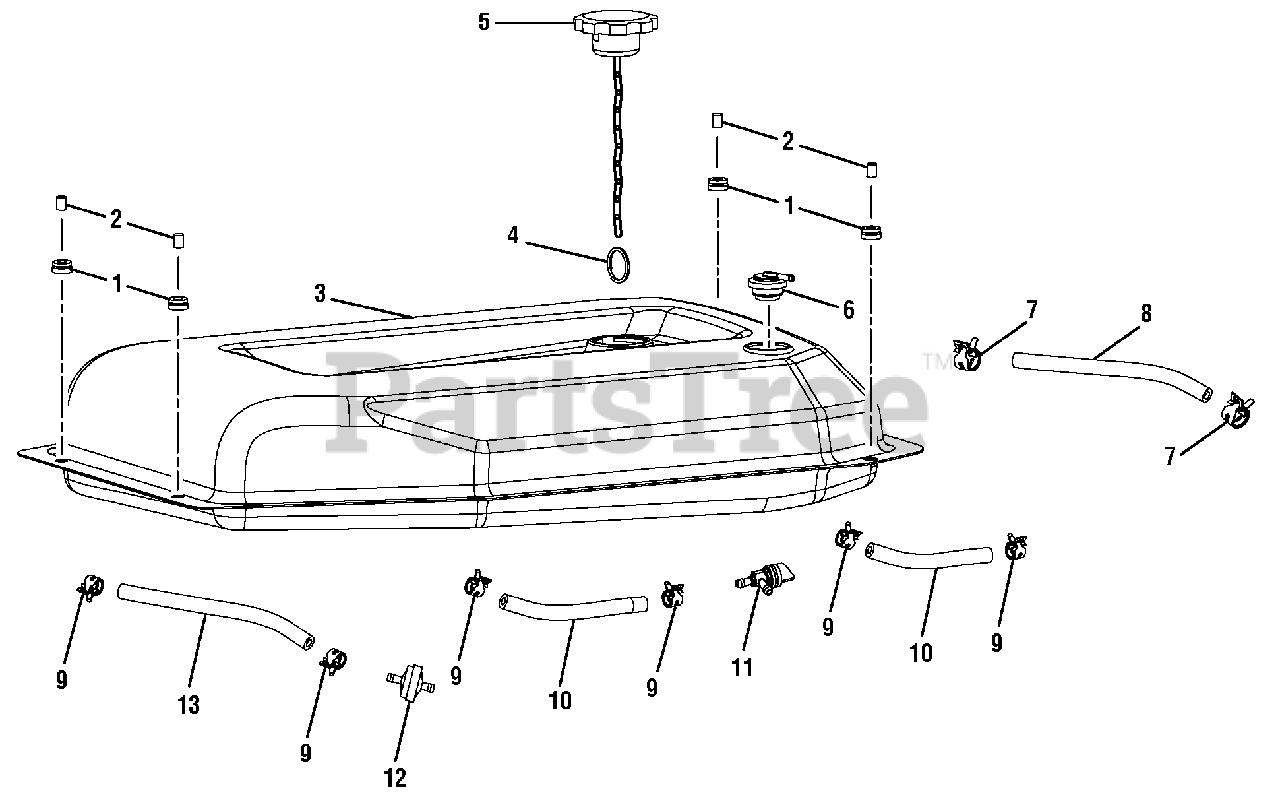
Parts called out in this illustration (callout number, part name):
1	Bushing (Fuel Tank Isolator)
2	Spacer (Fuel Tank Isolator)
3	Fuel Tank
4	Ring Clip
6	Fuel Tank Vapor Vent
7	Fuel Line Clamp (7/16 in.)
8	Vapor Hose
9	Fuel Line Clamp (1/2 in.)
10	Fuel Line (6.4 mm x 72 mm)
11	Fuel Shut Off Valve
12	Fuel Filter
13	Fuel Line (6.4 mm x 72 mm)
